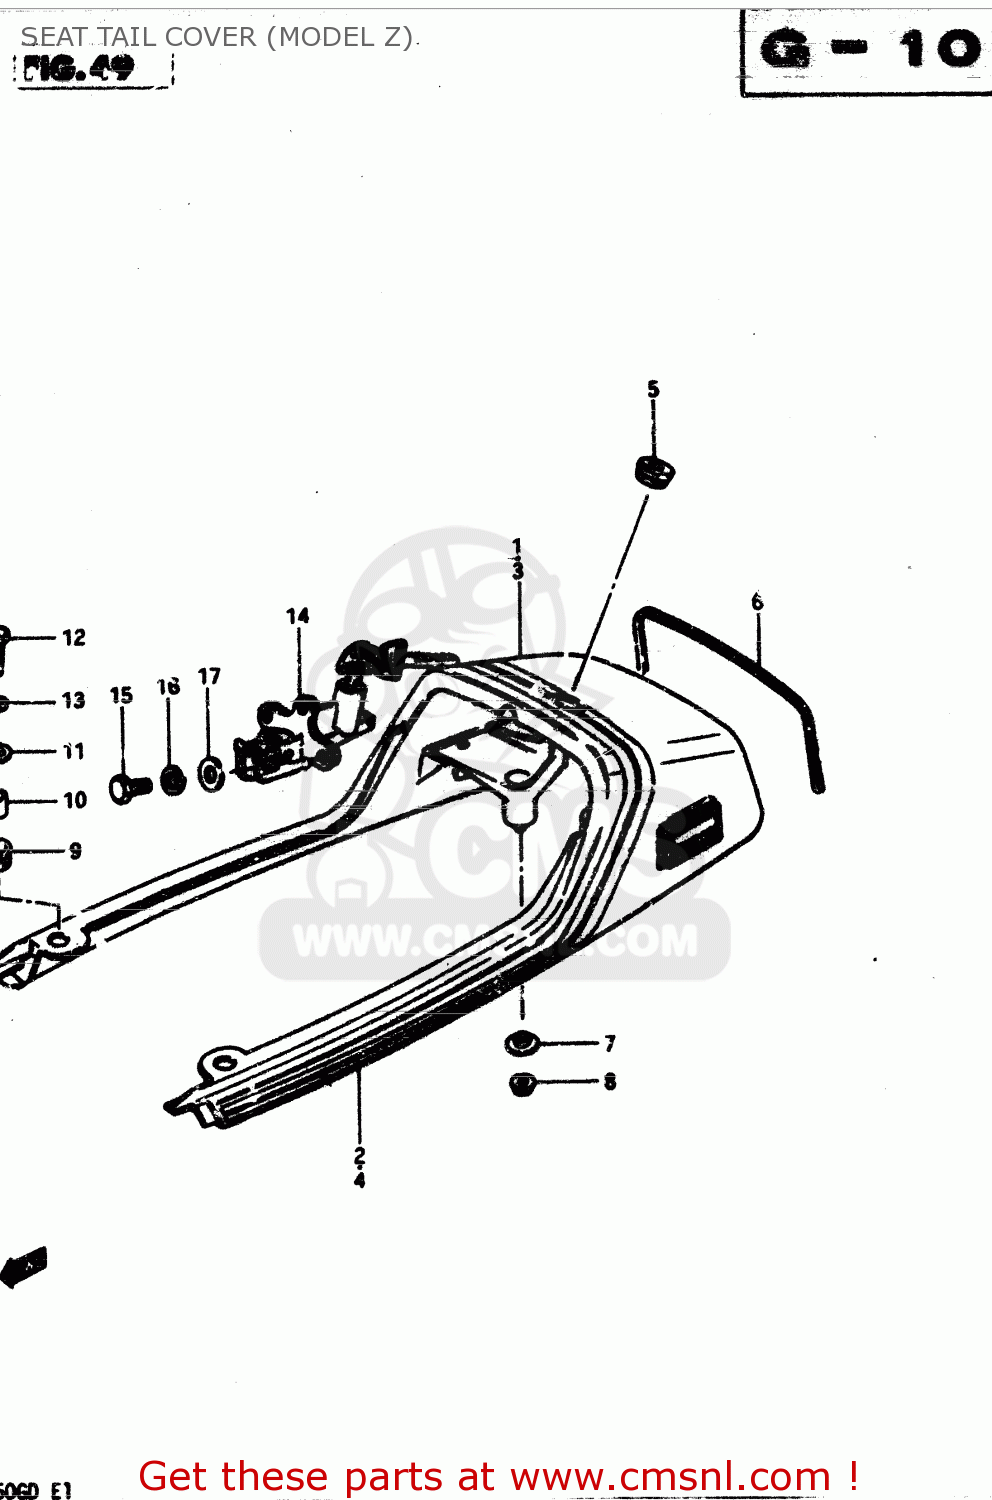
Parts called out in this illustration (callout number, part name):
1	COVER, SEAT TAIL (RED)
2	TAPE SET
3	COVER, SEAT TAIL (BLUE)
4	TAPE SET
5	GROMMET,SEAT LOCK HOLE
6	MOLDING,SEAT TAIL COVER
7	WASHER
8	NUT 6MM
9	CUSHION
10	SPACER (7X10X12)
11	WASHER (6.5X24X1.6)
12	BOLT
13	LOCK WASHER
14	LOCK SET,SEAT
15	BOLT
16	LOCK WASHER
17	WASHER
